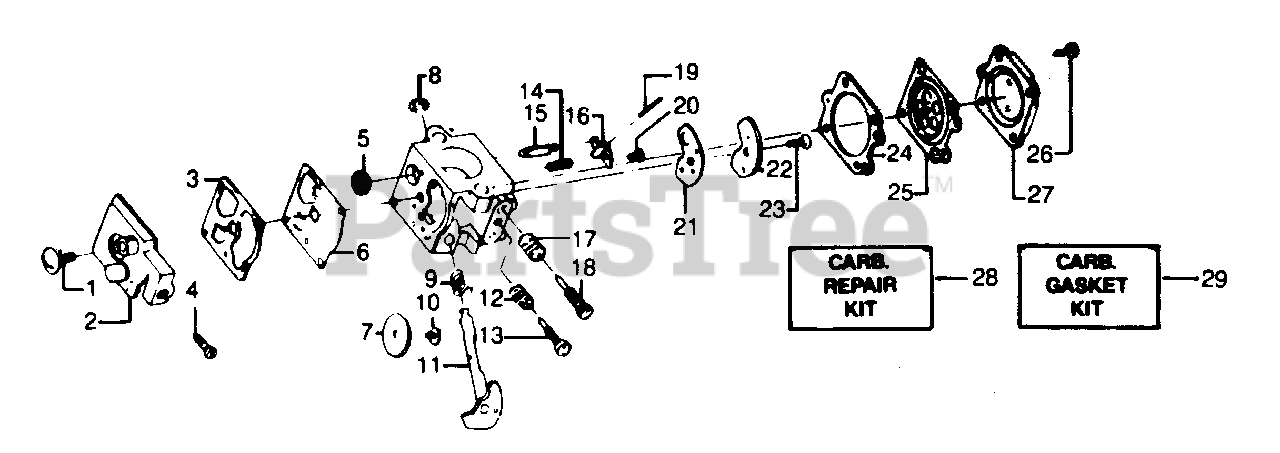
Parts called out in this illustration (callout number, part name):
1	Screw - Pump Cover
2	Pump Cover Ass'y (Inc.4)
3	Gasket - Pump
4	Screw - Idle Adjustment
5	Screen - Inlet
6	Diaphragm - Pump
7	Valve - Throttle
8	Clip - Throttle Shaft
9	Spring - Throttle Return
10	Screw - Throttle Valve
11	Shaft Assembly - Throttle
12	Spring - Idle Needle
13	Needle - Idle
14	Spring - Metering Lever
15	Valve - Inlet Needle
16	Lever - Metering
17	Spring - Hi Speed Needle
18	Needle - Hi Speed
19	Pin - Metering Lever
20	Screw - Metering Lever Pin
21	Gasket - Circuit Plate
22	Plate - Circuit
23	Screw - Circuit Plate
24	Gasket - Metering Diaphragm
25	Diaphragm Assembly - Metering
26	Screw Assembly - Metering Cover & Throttle Shaft Clip
27	Cover - Metering Diaphragm
28	Kit - Carb. Kwik Repair Kit
29	Kit - Carb. Gasket / Diaphragm
